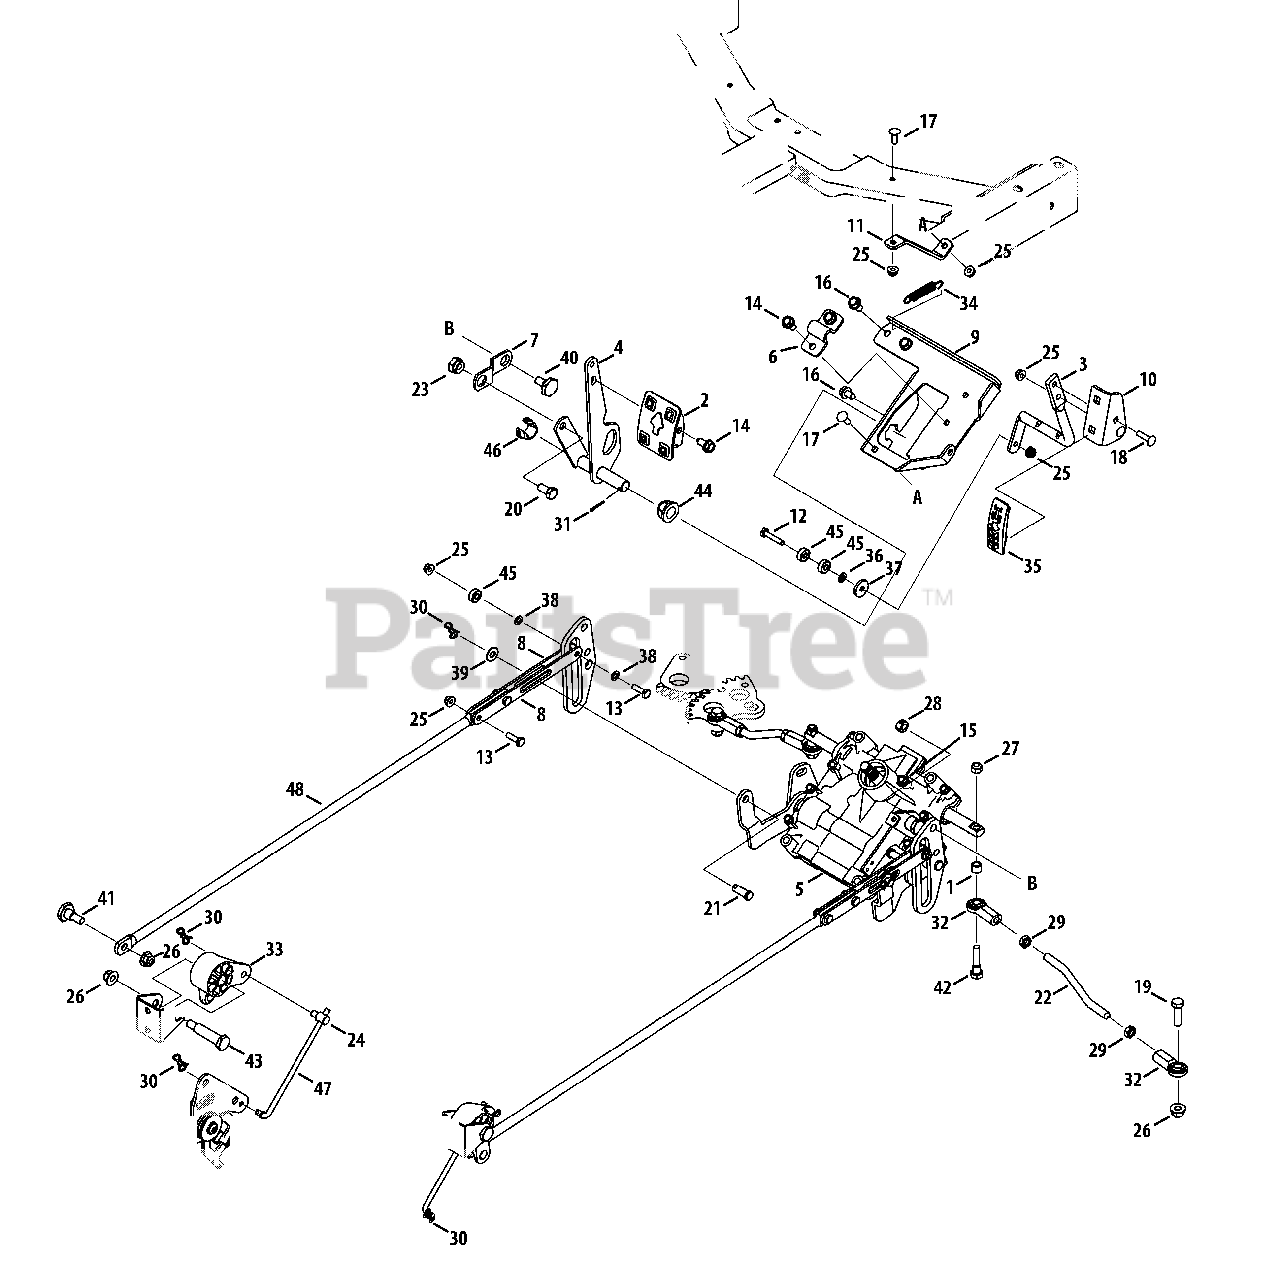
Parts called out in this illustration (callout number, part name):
1	Spacer, 344 x .500 x .375
2	Forward Pedal Assembly
3	Reverse Pedal Rod
4	Forward Bracket Assembly
5	Steering Assembly
6	Reverse Bearing Bracket
7	Control Bracket
8	Steering Link Plate
9	Pedal Mount Bracket
10	Reverse Pedal Bracket
11	Pedal Mount Plate Support Bracket
12	Hex Head Screw, 1/4-20 x 1.25
13	Hex Screw, 1/4-20 x .875
14	Hex Washer Screw, 5/16-18 x .750
15	Hex Washer Screw, 1/4-20 x .500
16	Hex Washer Screw, 5/16-18 x .625
17	Carriage Screw, 1/4-20 x .75
18	Carriage Screw, 1/4-20 x 1.00
19	Hex Screw, 3/8-16 x 1.25
20	Hex Screw, 3/8-16 x .750
21	Clevis Pin, .375 x .969
22	Rod, 3/8 x 5.0
23	Neutral Adjustment Hub
24	Adjustment Ferrule, 1/4-28 x 1.000
25	Flange Lock Nut, 1/4-20
26	Flange Lock Nut, 3/8-16
27	Hex Lock Nut, 5/16-24
28	Hex Lock Nut, 3/8-16
29	Jam Nut, 3/8-24
30	Bow-Tie Cotter Pin, 72
31	Cotter Pin, 3/32 x .750
32	Femaile Ball-Joint
33	Pivot Arm, LH
33	Pivot Arm, RH
34	Extension Spring, .429 x 2.515
35	Reverse Foot Pad
36	Flat Washer, .281 x .500 x .063
37	Flat Washer, .265 x .938 x .120
38	Flat Washer, .281 x .50 x .04
39	Thrust Washer, .375 x .812 x .060
40	Shoulder Screw, .625 x .217
41	Shoulder Screw, .500 x .434
42	Shoulder Screw, 375 x .48
43	Shoulder Screw, .500 x 1.825
44	Hex Flange Bearing
45	Ball Bearing, .25 x .6875 x .25
46	Hex Flange Bearing, .628
47	Hydro Control Rod
48	Hydro Link Rod
